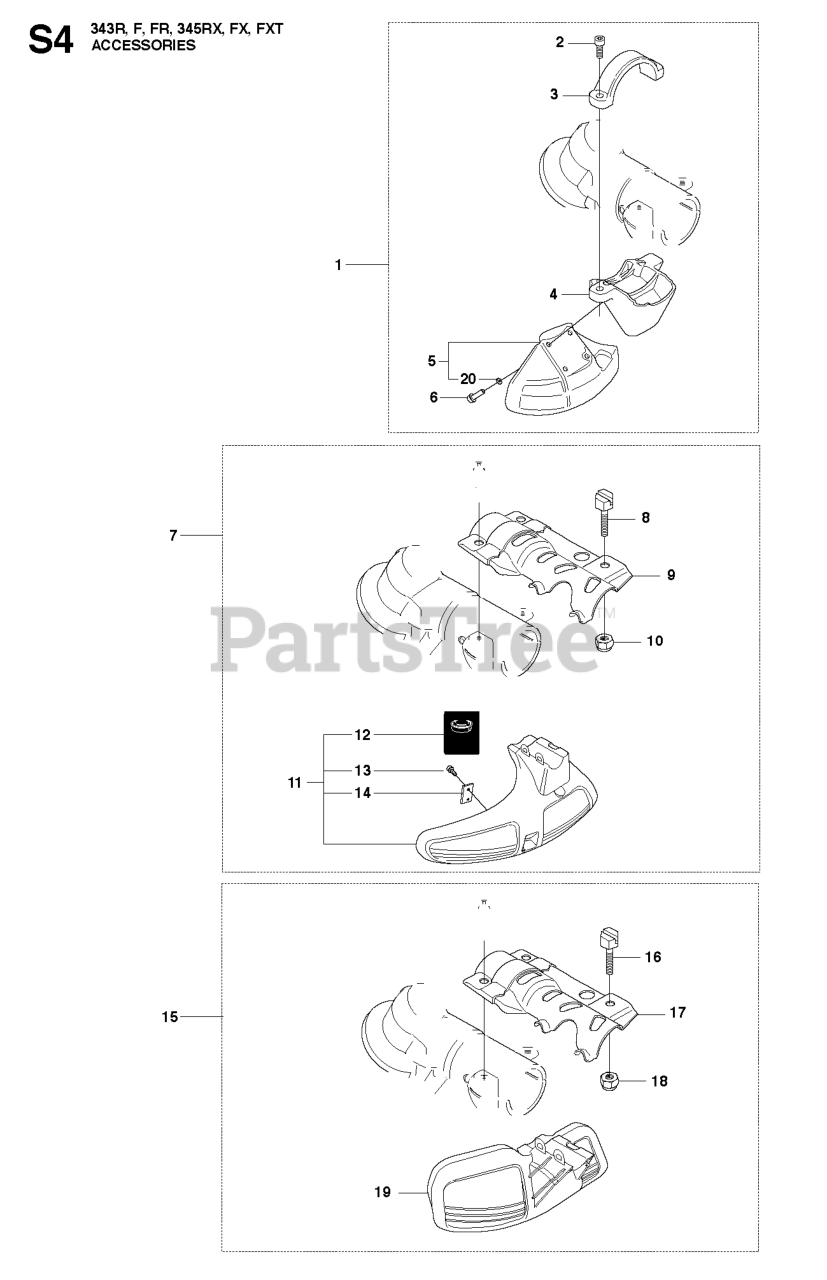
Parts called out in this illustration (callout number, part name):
1	TRIMMER GUARD ASSY
2	SCREW IHSCFMO
5	RP BLADE GUARD
7	TRIMMER GUARD ASSY
10	LOCKNUT M6
15	TRIMMER GUARD COMPL
18	LOCKNUT M6
19	BLADE GUARD
20	LOCKING NUT
